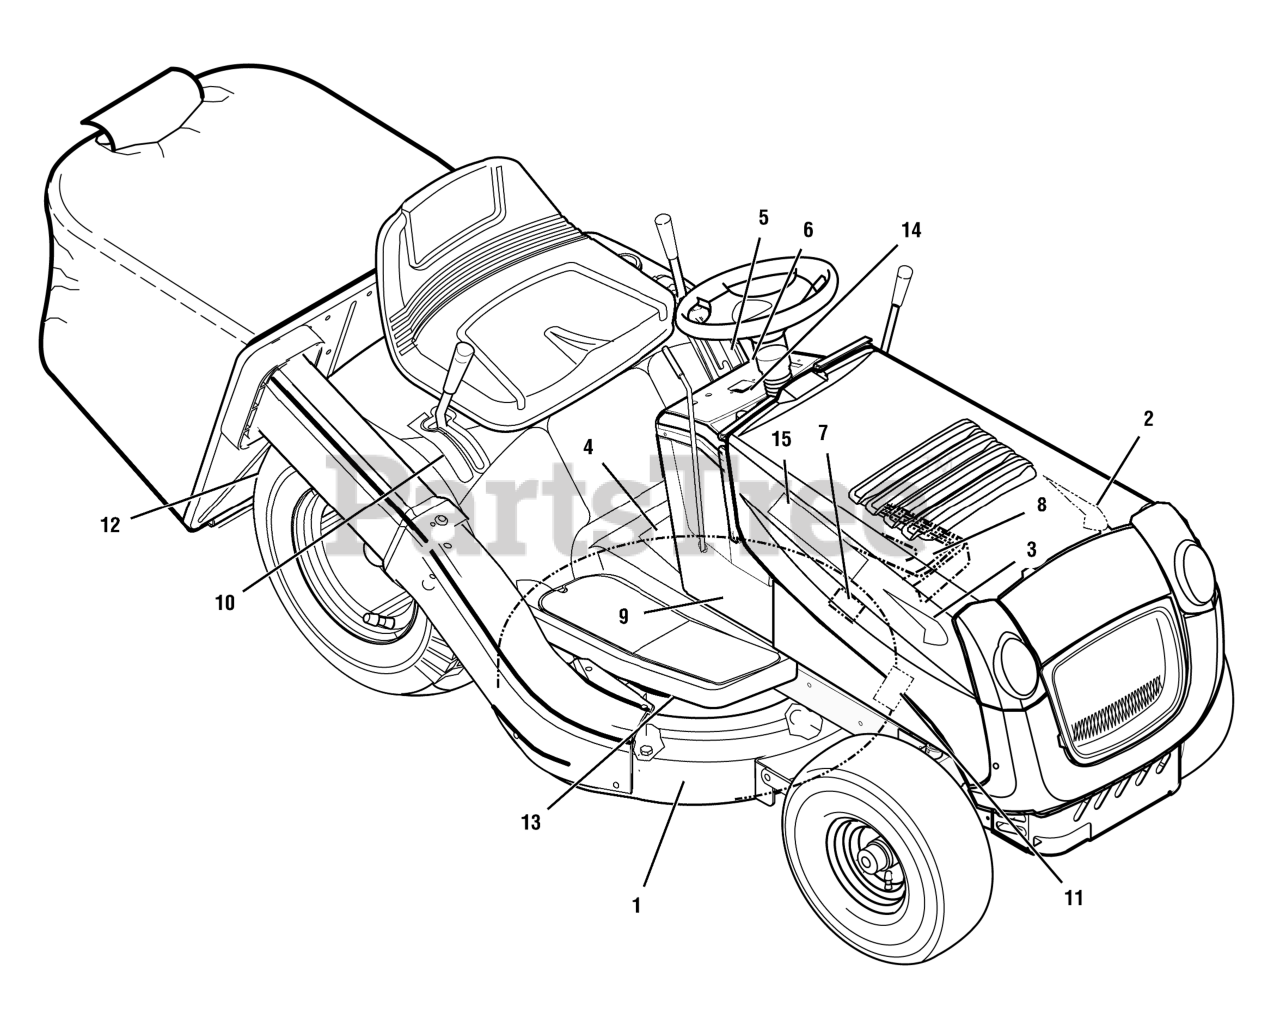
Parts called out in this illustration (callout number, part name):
720	HANDLE, UPPER LH
721	HANDLE, UPPER RH
723	SCREW
724	SCREW
725	WASHER, FLAT
726	WASHER, SPTLK
727	NUT, REGHEX
728	STOP, PLASTIC
729	GRIP-HANDLE
730	LEVER, ASSY CLUTCH DRIVE RH
731	LEVER, ASSY CLUTCH DRIVE LH
741	CABLE, AUGER CLUTCH
742	CABLE, TRACTON DRIVE
743	BRACKET, CABLE ADJUSTER
744	SPRING, AUGER CLUTCH
745	NUT, 1/4-20
748	GRIP, CLUTCH HANDLE
750	HANDLE, LOWER
752	WASHER, SPTLK
754	SCREW
755	BRKT, ROD
756	SCREW
757	SPRING, CAM LOCK
758	BOLT, HEX
759	NUT
761	SCREW
762	WASHER, FLAT
764	NUT, HEXFLNG
765	BOOT, CLUTCH SPRING
767	BOLT, HEX 1/4-20 X 1.75 YZ
768	CABLE, LOWER DRIVE 12
769	BRACKET, CABLE SPOOL YZ
771	SPOOL-CABLE, AUGRT CLUTCH
